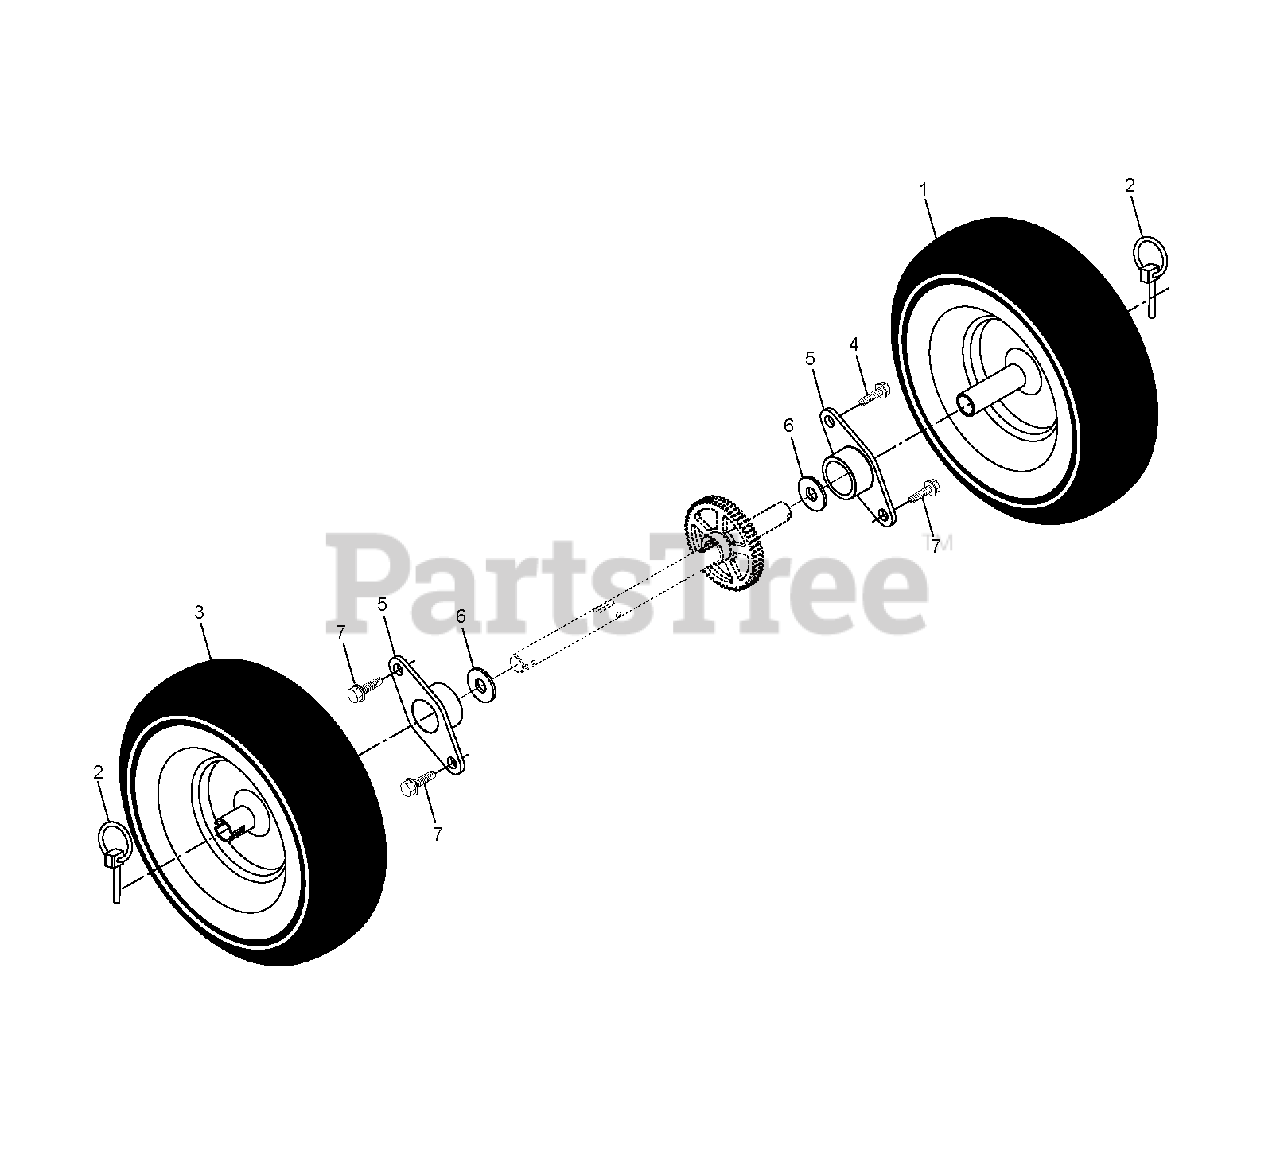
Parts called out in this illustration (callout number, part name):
1	WHEEL.ASM.LT.16"GRY.XTRAC
2	PIN KLIK, 1/4
3	WHEEL.ASM.RT.16".GRAY.XTRAC
5	BEARING, AXLE
6	WASHER TRUST 1"
7	SCREW, HEX HEAD 5/16-18 X 1/2
